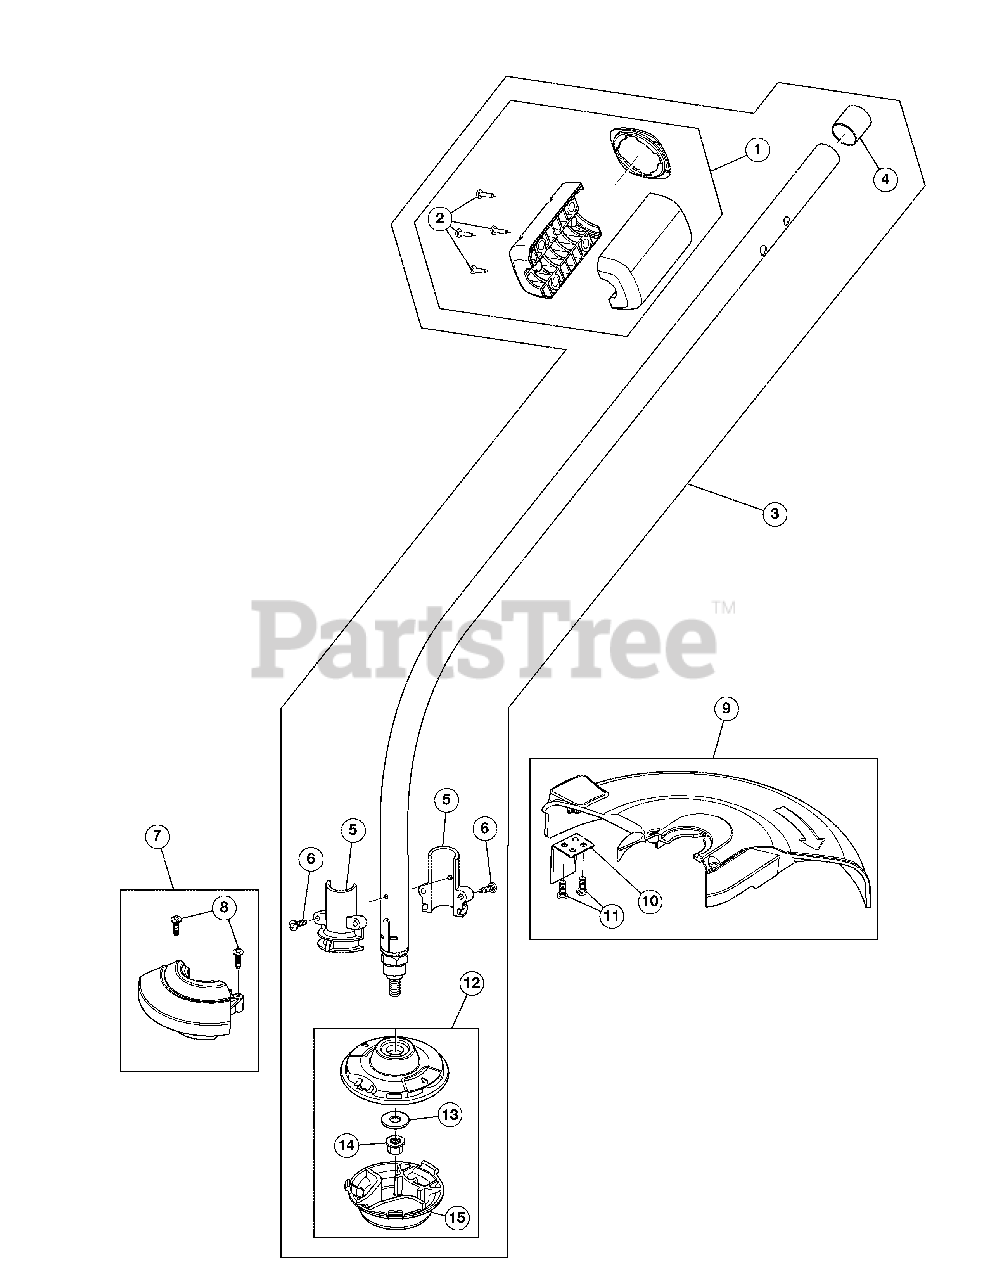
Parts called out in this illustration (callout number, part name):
1	Lower Drive Shaft Housing Extension Assembly
2	Screws
3	Lower Drive Shaft Housing Assembly
4	Hanger
5	Hub Guard Assembly
7	Front Shield Assembly
8	Screws
9	Rear Shield Assembly
10	Blade Assembly
11	Screws
12	Cutting Head Assembly
13	Washer
15	Glide Cap
